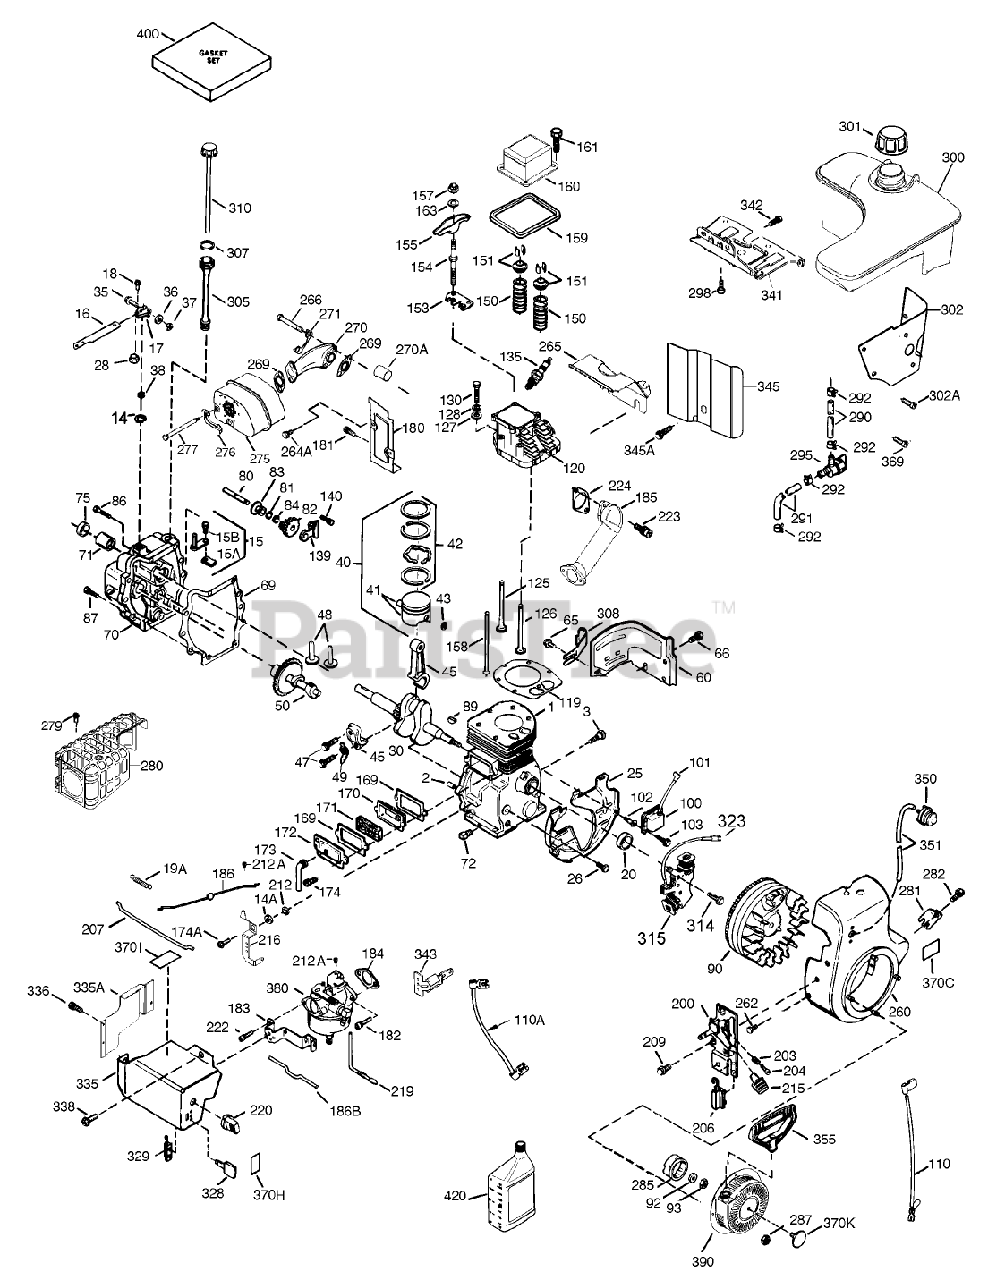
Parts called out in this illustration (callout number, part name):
1	Cylinder (Incl. Ref.# 2, 20, and 72)
2	Pin-Dowel
3	Screw (1/4-20x1/2)
14	Washer-Flat
14A	Washer
15	Rod, Governor (Incl. Nos.62 63)
15A	Yoke-Governor
15B	Screw (6-40x5/16)
16	Governor Lever
17	Clamp-Lever, Governor
18	Screw (T-15, 8-32x7/16)
19A	Spring-Extension
20	Seal-Oil
25	Baffle-Housing, Blower
26	Screw (1/4-20x19/32)
28	Nut-Lock
30	Crankshaft
35	Screw
36	Washer-Lock
37	Nut-Lock
38	Ring-Retaining
40	TANK PAD
40	Piston- Pin and Ring Set (.010 O S)
41	Piston and Pin ASM (STD) (Includes 43)
41	J-BOLT
42	BUSHING TRANS 7/8 BORE
42	BUSHING - ENG 1" BORE
45	Connecting Rod Asm (Includes 47, 49)
47	Bolt-Rod, Connecting
48	Lifter-Valve
49	Dipper-Oil
50	Camshaft
60	Extension-Housing, Blower
65	Screw (10-24 x 9/16)
66	Screw
69	Gasket-Cover, Cylinder
70	Cover-Cylinder (Incl. Ref. #14, 15, 38, 71, 75)
71	2025A77 WIZARD ROTA
72	Plug-Drain, Oil (SQH 1/4-18)
75	Seal-Oil
80	Shaft-Governor
81	Washer-Flat
82	Gear Assy., Governor (Incl. Ref. #45)
83	Spool-Governor
84	Ring-Retaining
86	Screw (1/4-20x1-3/16)
87	Screw (1/4-20x1-11/16)
89	Key-Flywheel
90	Flywheel ASM
92	Washer-Belleville
93	Nut-Flywheel
100	Solid State ASM
101	Cover-Spark Plug
102	Stud-Mounting, Solid State
103	Screw (T-15, 10-24 x 15/16)
110	Wire-Ground
110A	Wire-Ground
119	Gasket-Head, Cylinder
120	Cylinder Head
125	Valve-Exhaust (STD)
125	Valve-Exhaust (1/32)
126	Valve-Intake (STD)
126	Intake Valve (1/32)
127	Washer-Flat
128	Washer-Belleville
130	Screw (5/16-18 X 2-1/2)
135	Spark Plug-Resistor (R N 4C)
139	Bracket-Gear, Governor
140	Screw (10-24x1/2)
150	Spring-Valve
151	Keeper-Spring, Valve
153	Guide-Rod, Push
154	Stud-Arm, Rocker
155	Arm-Rocker
157	Nut-Jam
158	Rod-Push
159	Gasket-Cover, Rocker Arm
160	Cover-Arm, Rocker
161	Screw
163	Washer
169	Gasket-Cover, Valve
170	Body-Breather
171	Element-Breather
172	Cover-Valve
173	Tube-Breather
174	Screw
174A	Screw (10-24 X 29/32)
180	Extension-Housing, Blower
181	Screw (10-24 x 9/16)
182	Screw (T-30, 1/4-20 X 27-32)
183	Bracket-Choke
184	Gasket-Carburetor To Intake Pipe
185	Pipe-Intake
186	Link-Governor
186B	Spring-Choke
200	Bracket-Control (Incl. Ref. #203, 204 and 206)
203	Spring-Compression
204	Screw (T-10, 5-40x7/16)
206	Terminal
207	55106 TWO WHEEL TRA
209	Screw (10-32 x 1/2)
212	Bushing
212A	Bushing
215	Knob-Control
216	Lever-Bellcrank
219	Rod-Choke
220	Knob-Control
222	Screw (10-32 x 1/2)
223	Screw (T-30, 5/16-18 X 7/8)
224	Gasket-Pipe
260	Housing-Blower
262	Screw
264A	Screw (1/4-20 X 5/8)
265	Cover-Head, Cylinder
266	Screw (5/16-18 X 1-9/32)
269	Gasket-Manifold, Exhaust
270	55107 SNWTHWR ATTCH
270A	Liner-Port, Exhaust
271	Plate-Locking
275	Muffler
276	Locking Plate
277	Screw (5/16-18 X 4-1/2)
279	Screw
280	Shield-Heat, Radiation
281	Screw
282	Screw (8-32 x 3/8)
285	Cup-Starter
287	Nut and Lock Washer (1/4-28)
290	Line-Fuel
291	Line-Fuel (8.62)
292	Clamp-Line, Fuel
295	Valve-Shut Off, Fuel
298	Screw (1/4-15x7/8)
300	Fuel Tank (Incl. 292 and 301)
301	Cap-Fuel
302	Extension-Tank, Fuel
302A	Screw (10-32 x 1/2)
305	Tube-Fill, Oil
307	O-Ring
308	Clip-Tube, Fill
310	Dipstick
314	Screw (1/4-20 x 3/4)
315	Coil-Alternator, 18 Watt (Includes 323)
323	Terminal
328	Key-Ignition
329	Terminal
335	Spring
335A	Cover-Carburetor
336	Screw (10-32 x 1/2)
338	Screw (10-32 x 1/2)
341	Bracket-Tank, Fuel
342	Screw (5/16-18 X 7/8)
343	Bracket-Switch, Key
345	Baffle-Heat
345A	Screw (10-32 x 1/2)
350	Primer ASM
351	Line-Primer
355	Handle-Starter, Mitten Grip
370C	Decal-Primer, International Symbol
370H	Decal-Choke
370I	Decal-Warning (Bilingual)
380	Carburetor (Incl. Ref.# 184)
390	Starter-Rewind
400	Gasket Set
420	Oil-Engine, S A E 5W30
